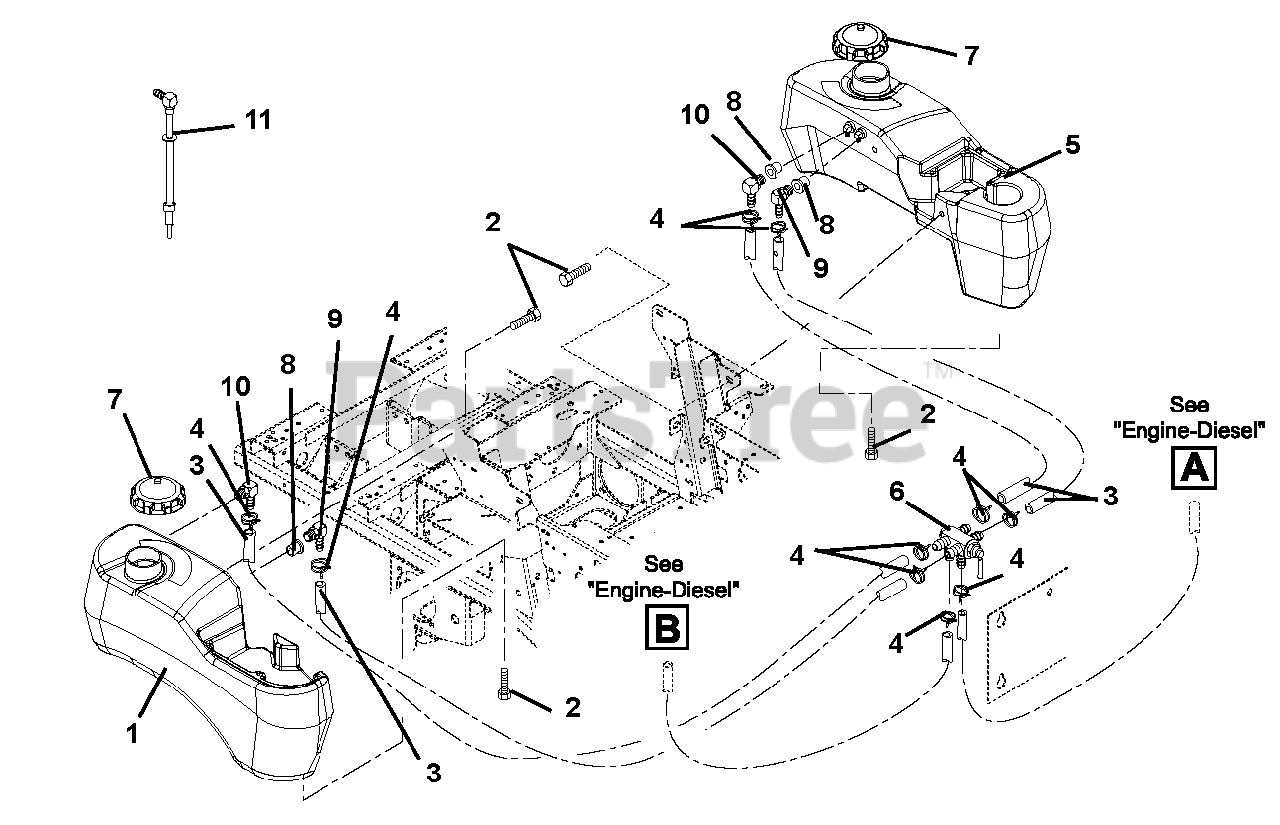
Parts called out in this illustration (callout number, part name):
1	Tank, Fuel-Right Hand
2	Bolt, SEMS .31-18 x .62
3	Hose, .31 ID
4	Clamp, Hose Wire .52/.55
5	Tank, Left Hand Fuel
6	Valve, Fuel
7	Cap, Fuel
8	Grommet, Orange
9	Fitting, Tank
10	Fitting, Tank
11	26" Fuel Line Kit, Diesel (Inside Tank)
